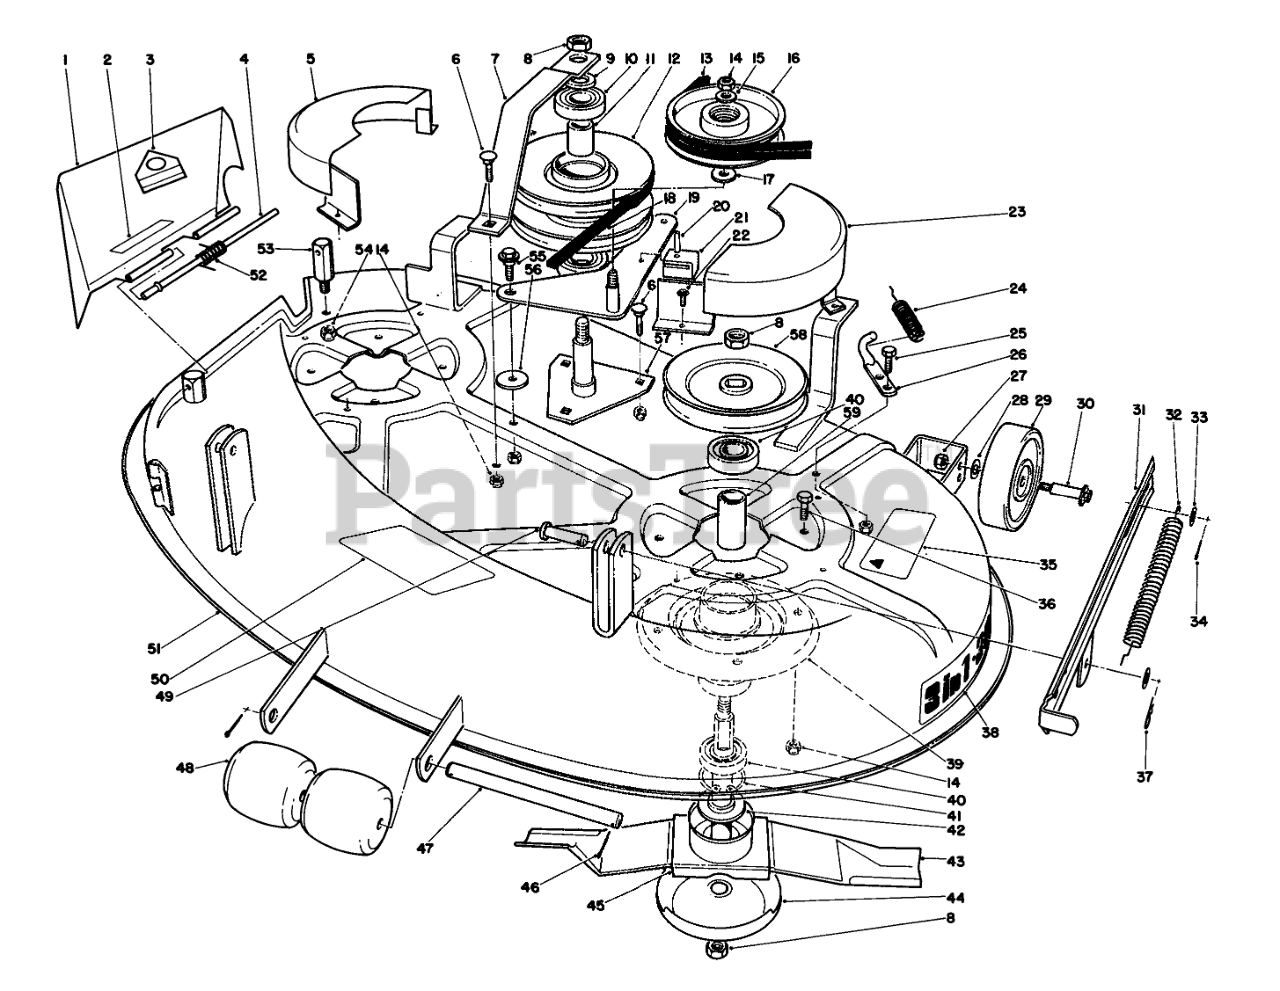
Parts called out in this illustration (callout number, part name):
1	Deflector Assembly (Incl. Ref. #2-3)
2	DECAL-NO STEP
3	DECAL-DANGER
4	ROD-HINGE DEFLECTOR
5	RH BELT COVER WA B
6	BOLT-CARR
7	Support-Pulley
8	NUT-LOCK NI
9	WASHER-FLAT
10	BEARING-BALL
11	TUBULAR SPACER
12	Pulley Assembly (Incl. Ref. #10-11)
13	V-BELT
14	NUT-LOCK, NI
15	WASHER-FLAT
16	PULLEY-IDLER
17	WASHER-FLAT
18	V-BELT
19	Bracket-Idler
20	PIN-COIL
21	IDLER BRKT GUIDE
22	SCREW-HWHTF
23	Cover-Belt L.H.
24	DECK TENSION SPRNG O
25	SCREW-HH
26	SPRING ROD
27	NUT-LOCK, NI
28	WASHER-FLAT
29	WHEEL-DECK
30	BOLT-WHEEL
31	Strap-Deck Spring (L.H.)
32	DECK TENSION SPRNG O
33	WASHER-FLAT
34	Cotter Pin
35	DECAL-CAUTION, BLADE
36	SCREW-HH
37	PIN-COTTER
38	DECK DECAL
39	Spindle
40	BEARING-BALL
41	RING-RETAINING
42	SPACER-SPINDLE
43	Blade
44	Cup
45	SPINDLE SHAFT WA
46	PIN-COTTER
47	ROLLER SHAFT
48	ROLLER
49	PIN-CLEVIS
50	BELT RTG DECAL
51	DECK WA
52	SPRING
53	REAR PIVOT POST (PLTD)
54	NUT-LOCK, NI
55	SCREW-SHOULDER
56	WASHER-PIVOT
57	Jackshaft
58	DECK PULLEY
59	BEARING SPACER
